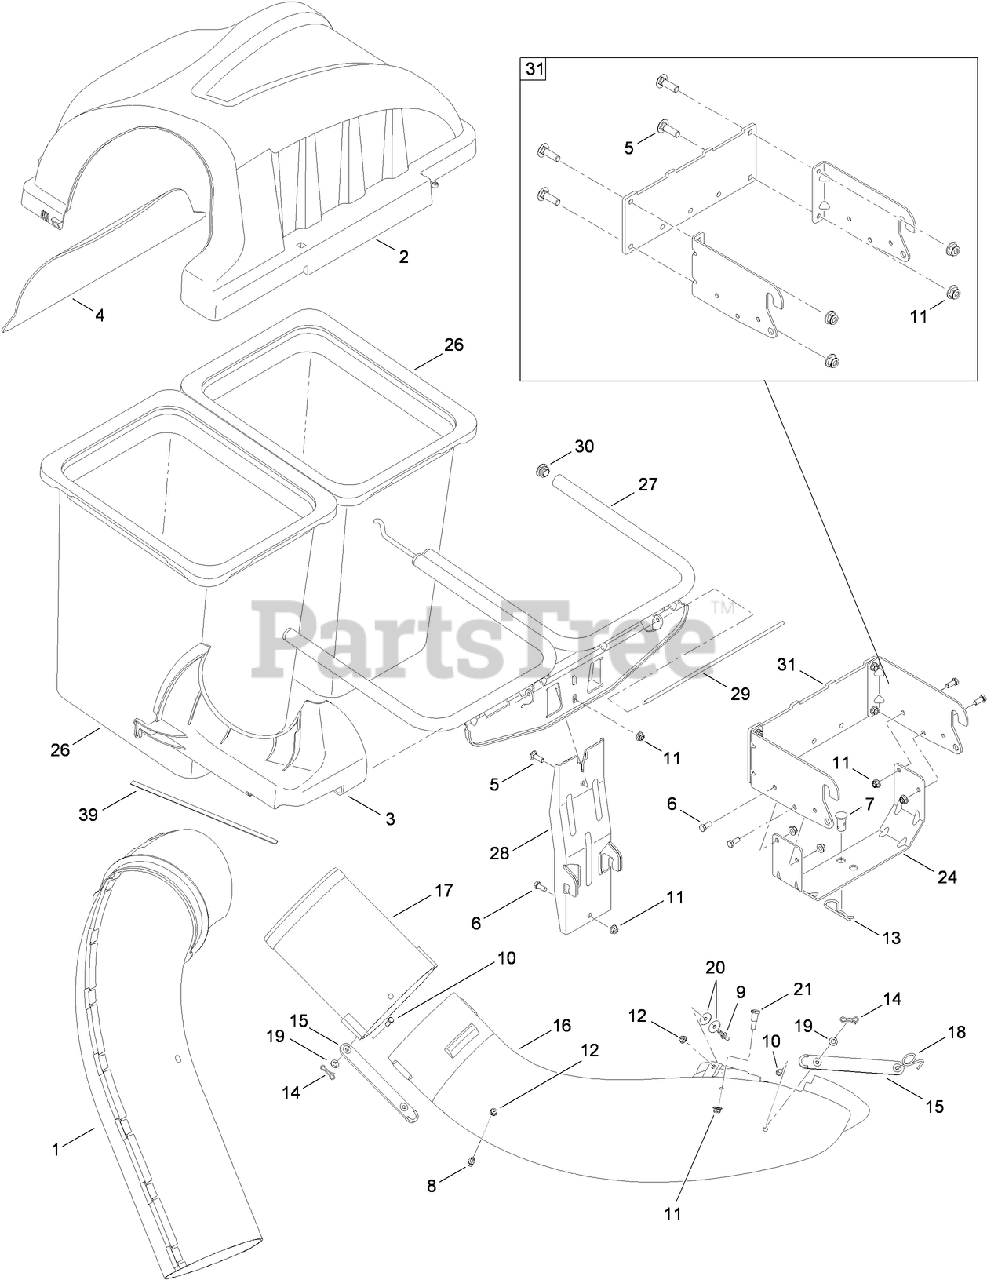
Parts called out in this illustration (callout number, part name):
1	UPPER CHUTE ASM
2	DOUBLE BAGGER COVER ASM
3	SUPPORT-CHUTE, UPPER
4	SCREEN-COVER, BAGGER
5	BOLT-CARR
6	SCREW-HH
7	PIN-CLEVIS
8	PIN-CATCHER, GRASS
9	PIN-ATTACHMENT
10	PIN-CLEVIS
11	NUT-LOCK, FLANGE
12	NUT-LOCK, FLANGE
13	CLIP-HAIRPIN
14	PIN-COTTER
15	STRAP-CHUTE
16	ELBOW-DISCHARGE CHUTE, BAGGER
17	ADAPTER-CHUTE, DISCHARGE
18	HOOK-SPRING, TORSION
19	WASHER-BELL
20	WASHER-FLAT
21	SCREW-SHOULDER
24	SUPPORT-BRACKET, UNIVERSAL
26	GRASS BAG ASM
27	DOUBLE BAG SUPPORT ASM
28	BRACKET-SUPPORT, VERTICAL
29	PIN-HINGE, COVER
30	PLUG-END
31	HITCH BRACKET ASM
39	FOAM STRIP-SELF ADHESIVE
